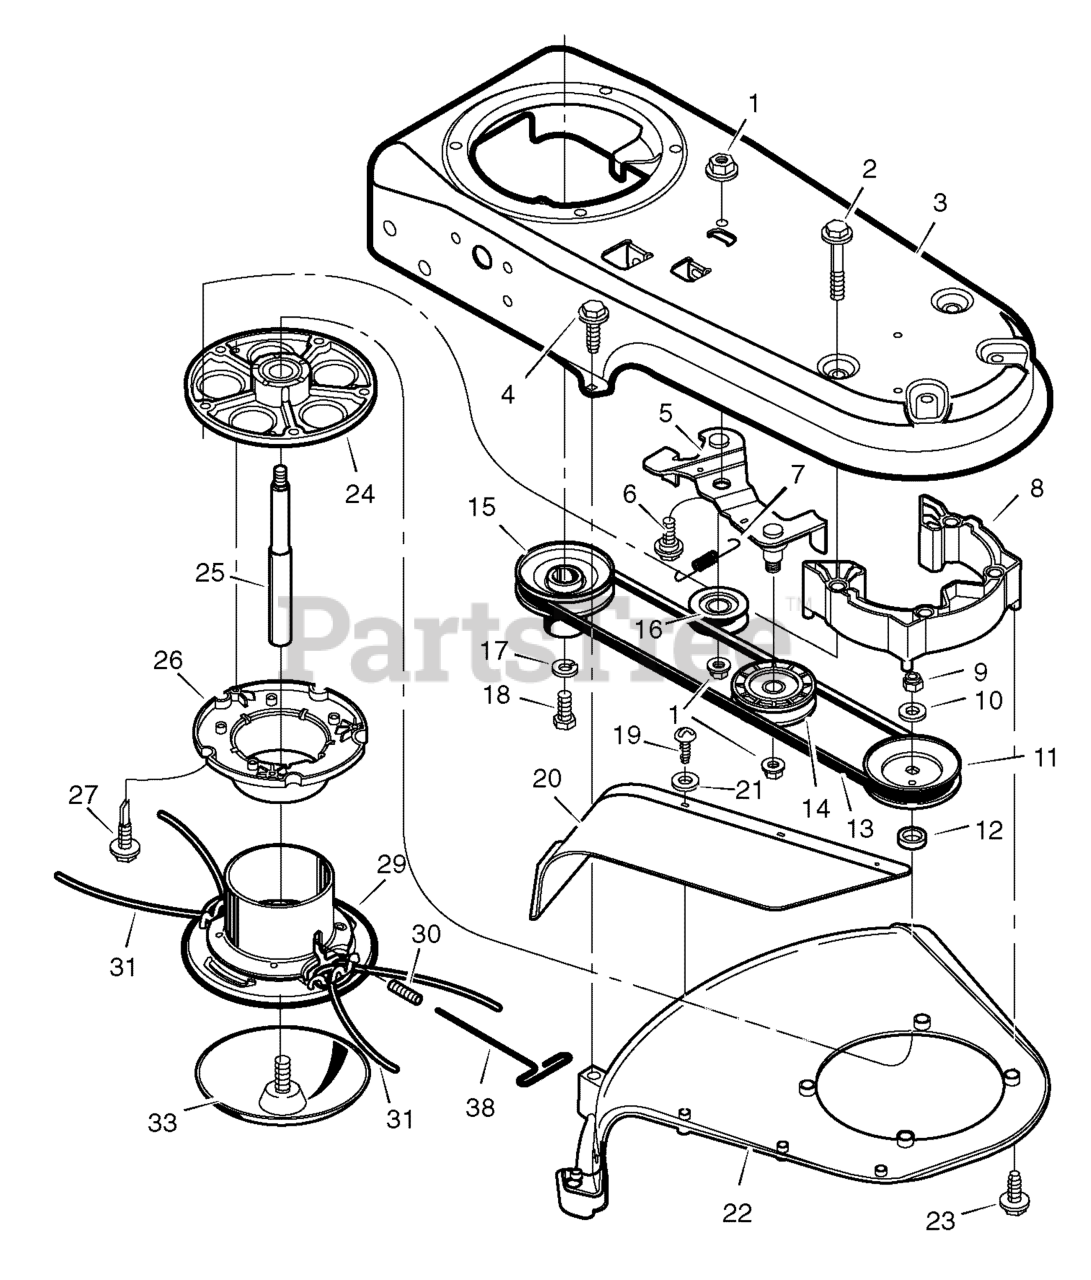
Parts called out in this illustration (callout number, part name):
1	NUT
3	FRAME, Trimmer
5	BRACKET, Idler Assembly
10	WASHER
11	PULLEY, Cutting Head
13	BELT
14	PULLEY, IDLER, V, 1.88
15	PULLEY, Engine
16	PULLEY, Idler
17	LOCKWASHER
20	FLAP, Debris
24	HOUSING, Jackshaft
25	SHAFT, Cutting Head
26	WRAP, Weed
29	ASSEMBLY, Cutter Head & Wrap
30	SCREW, Set
31	LINE, Trimmer 0.155x21-1/2
33	GUIDE, Metal Height
38	Wrench, T-Handle
